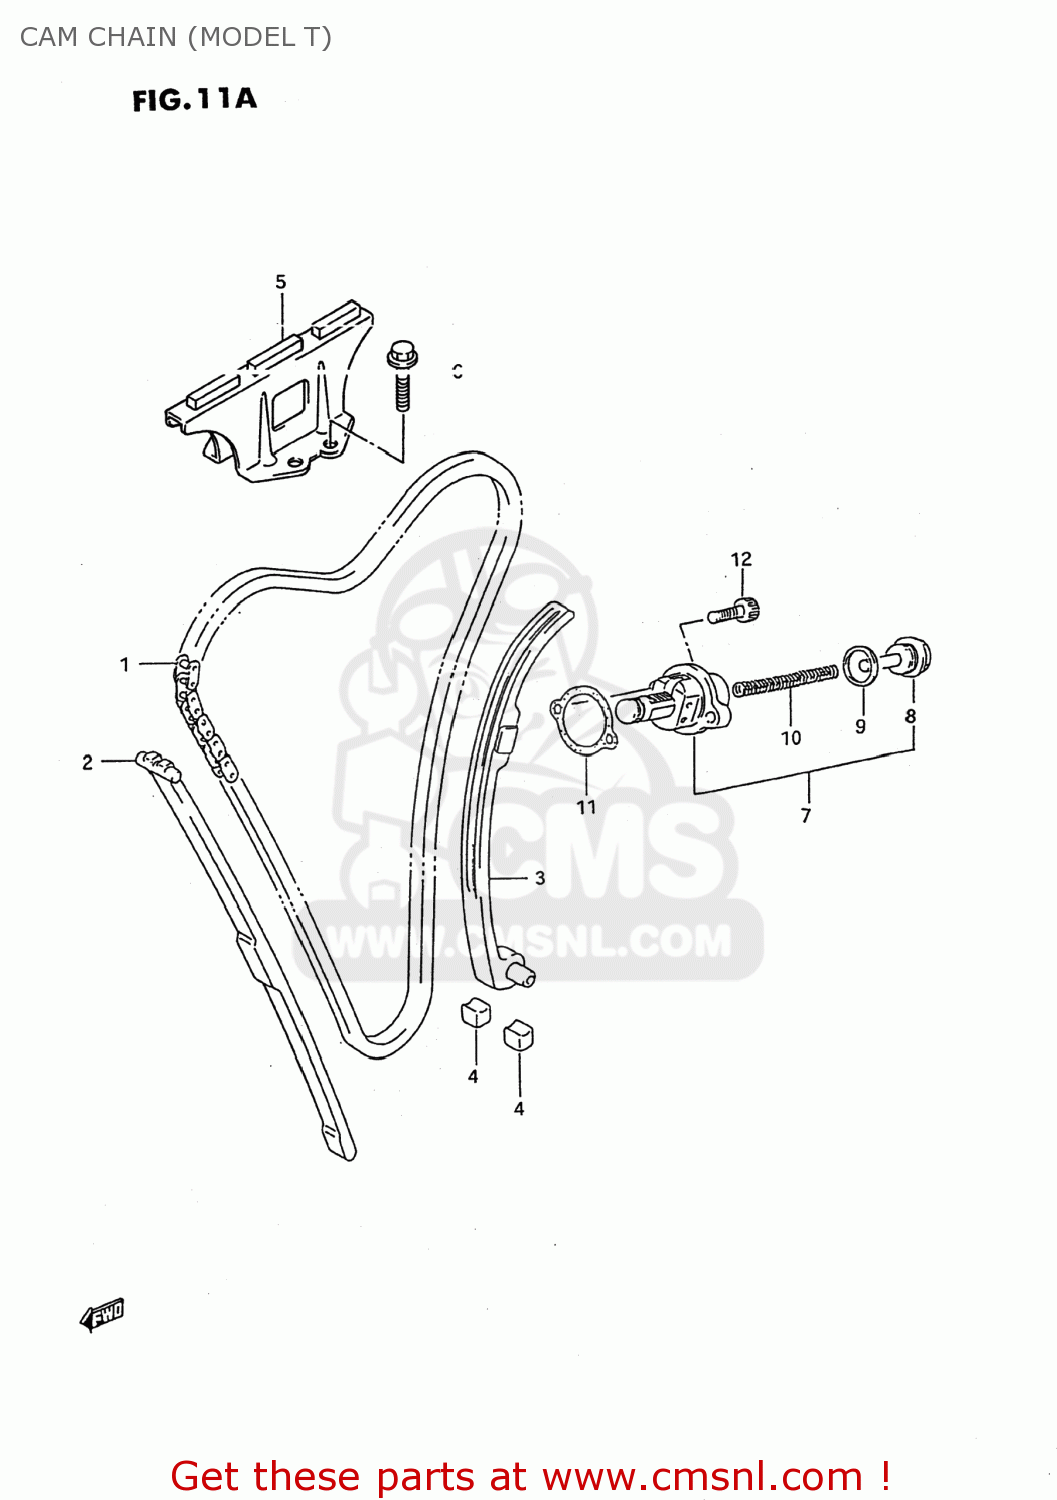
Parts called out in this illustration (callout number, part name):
1	CHAIN,CAMSHAFT DRIVE
2	GUIDE,CAM CHAIN NO.1
3	TENSIONER,CAM CHAIN
4	CUSHION,CAM CHAIN TENSIONER
5	GUIDE,CAM CHAIN NO.2
6	BOLT
7	ADJUSTER ASSY,TENSIONER
8	PLUG
9	GASKET (NAS)
10	SPRING
11	GASKET,TENSIONER ADJUSTER (NAS)
12	BOLT,CL.COVER
